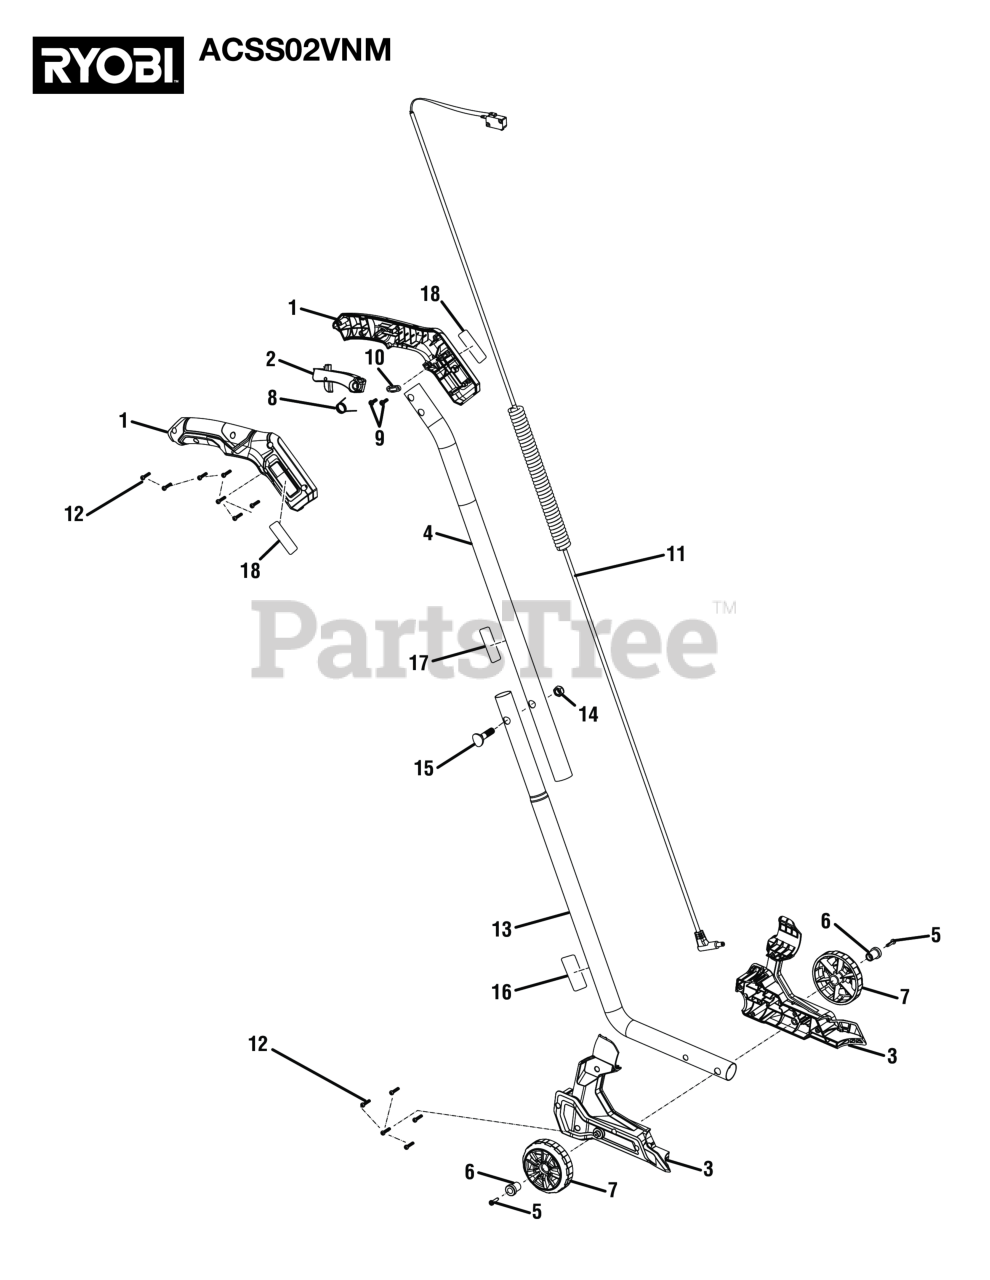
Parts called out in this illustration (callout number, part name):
1	Handle Housing Assembly
2	Trigger Assembly
3	Housing Assembly
4	Upper Tube Assembly
5	Screw (M4 x 22 mm Pan Hd.)
6	Wheel Shaft
8	Trigger Spring
9	Screw (M4 x 12 mm, Pan Hd.)
10	Strain Relief Plate
11	Switch Assembly
12	Screw (M3.5 x 12 mm, T15 Torx Pan Hd.)
13	Lower Tube Assembly
14	Flange Lock Nut (M8 x 1.25 mm)
15	Screw (M8 x 36 mm)
17	Data Label
18	Logo Label
